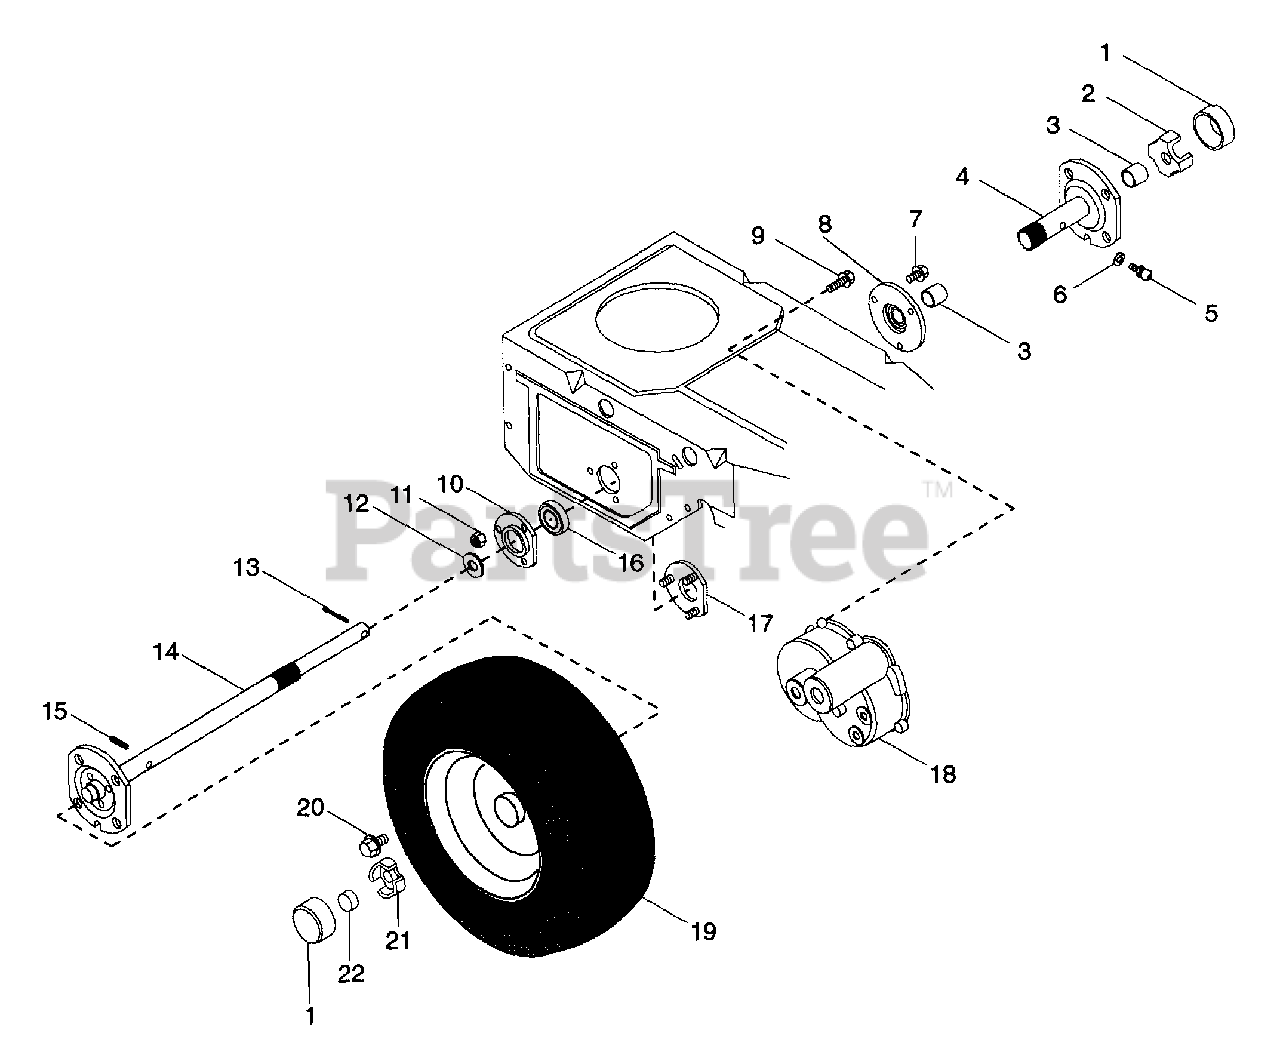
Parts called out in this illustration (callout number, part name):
1	HUB CAP
2	SPINDLE CUP
3	BSHG-SLV .690X.814X1.000 BR
4	L.H. AXLE ASSEMBLY
5	SPIN DRIVE ZERK FITTING
6	WSHR-LK .250X.047 LT PL
7	SCR-TAP.250-20X.62 HWH BLK ZC
8	SEAL 1.125X2.496X.380
9	SCR-TAP .312-18X1.50 HWH PL TR
10	BEARING FLANGE
11	NUT-LK-FLG .250-20 PL
12	WSHR-FL-STL .880X1.380X.062
13	PIN-COTR .12X1.0 PL
14	RH AXLE
15	PIN-ROLL .188X1.25
16	BRG-BALL .876 X 1.750 X .50
17	BEARING FLANGE
18	GEAR CASE ASSEMBLY
19	T/WHL ASSY 6.50-8 X 16
20	SCR-TAP .500-20X.62 HH PL
21	SPINDLE CUP
22	PUSHNUT
